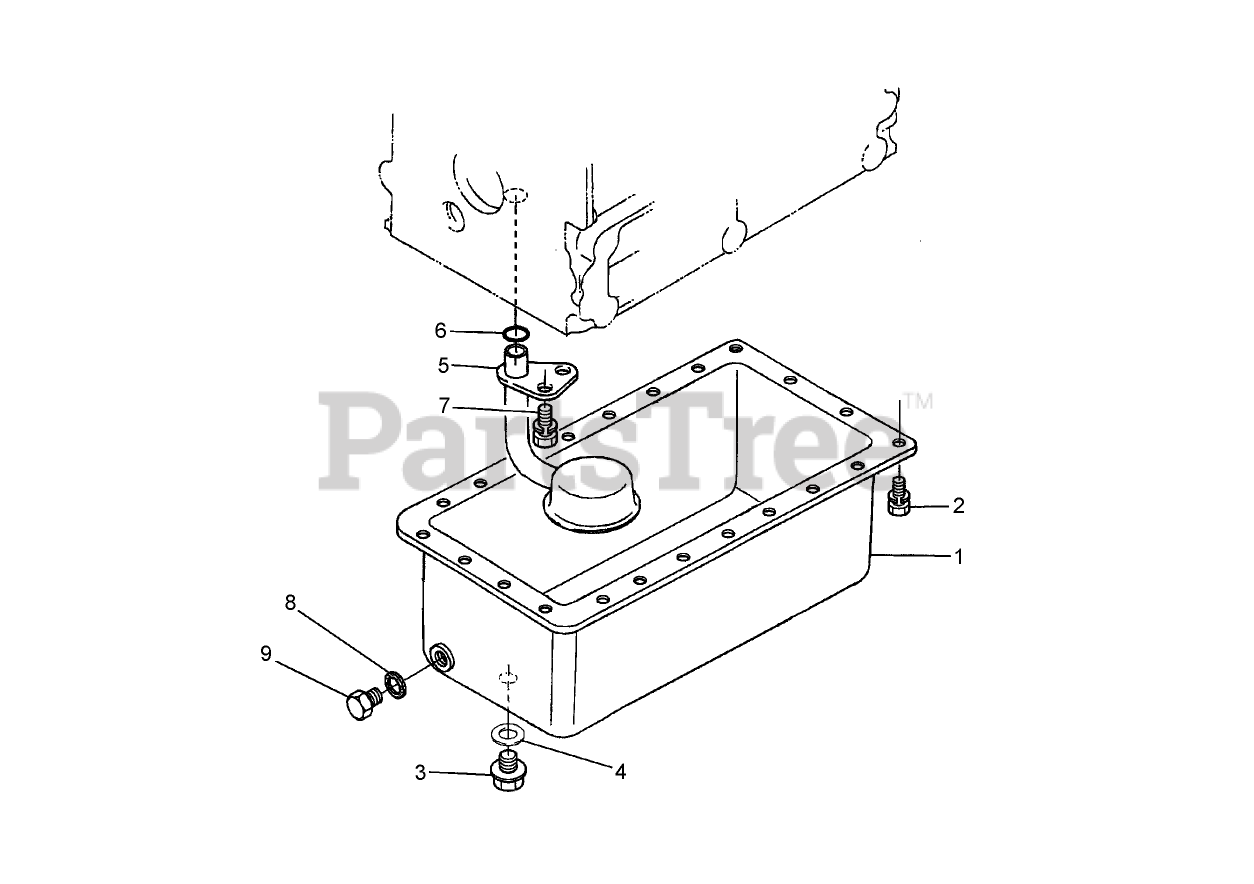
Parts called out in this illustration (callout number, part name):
1	OIL PAN ASM
3	PLUG-DRAIN
4	GASKET
5	STRAINER-PICKUP, OIL
6	O-RING
8	GASKET
9	PLUG-DRAIN
